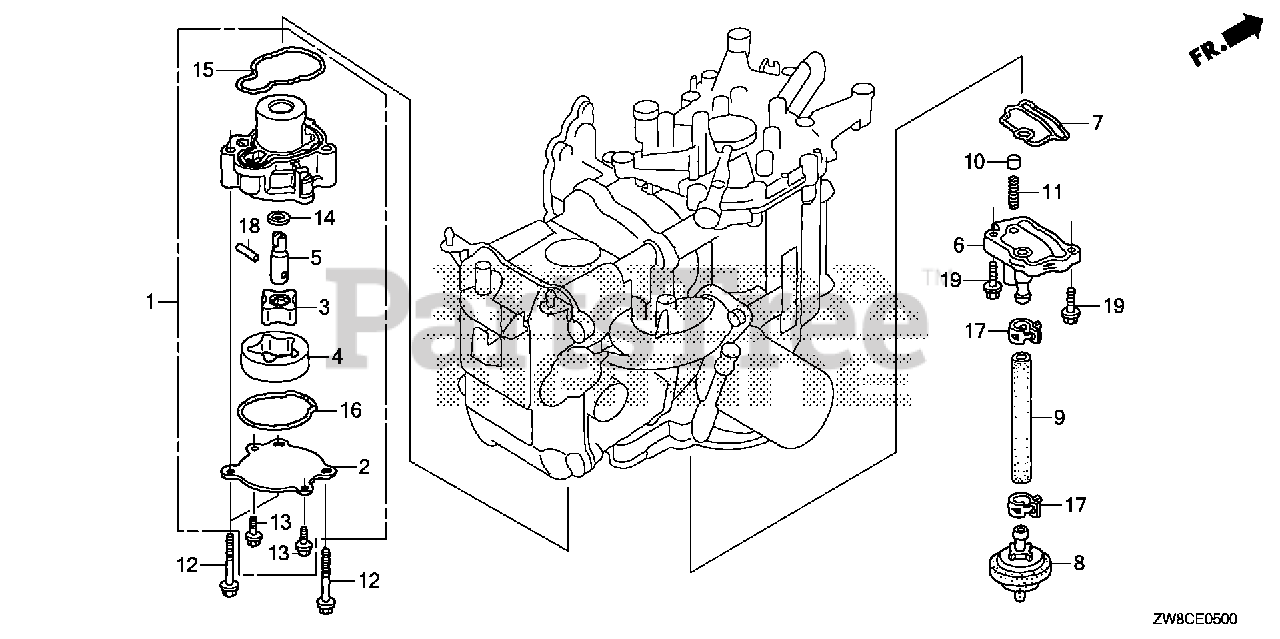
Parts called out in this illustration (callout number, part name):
1	PUMP ASSY., OIL
2	COVER, OIL PUMP
3	ROTOR (INNER)
4	ROTOR (OUTER)
5	SHAFT, OIL PUMP
6	FLANGE, OIL STRAINER
7	O-RING, OIL STRAINER FLANGE
8	STRAINER, OIL
10	VALVE, CHECK
11	SPRING, CHECK VALVE
12	BOLT, FLANGE (6X35)
13	BOLT, FLANGE (5X12) (CT200)
14	WASHER, THRUST (11MM)
15	O-RING, OIL PUMP
16	O-RING, PUMP COVER
17	CLAMP, TUBE (D17)
18	ROLLER (4X15.8)
19	BOLT, FLANGE (6X22)
